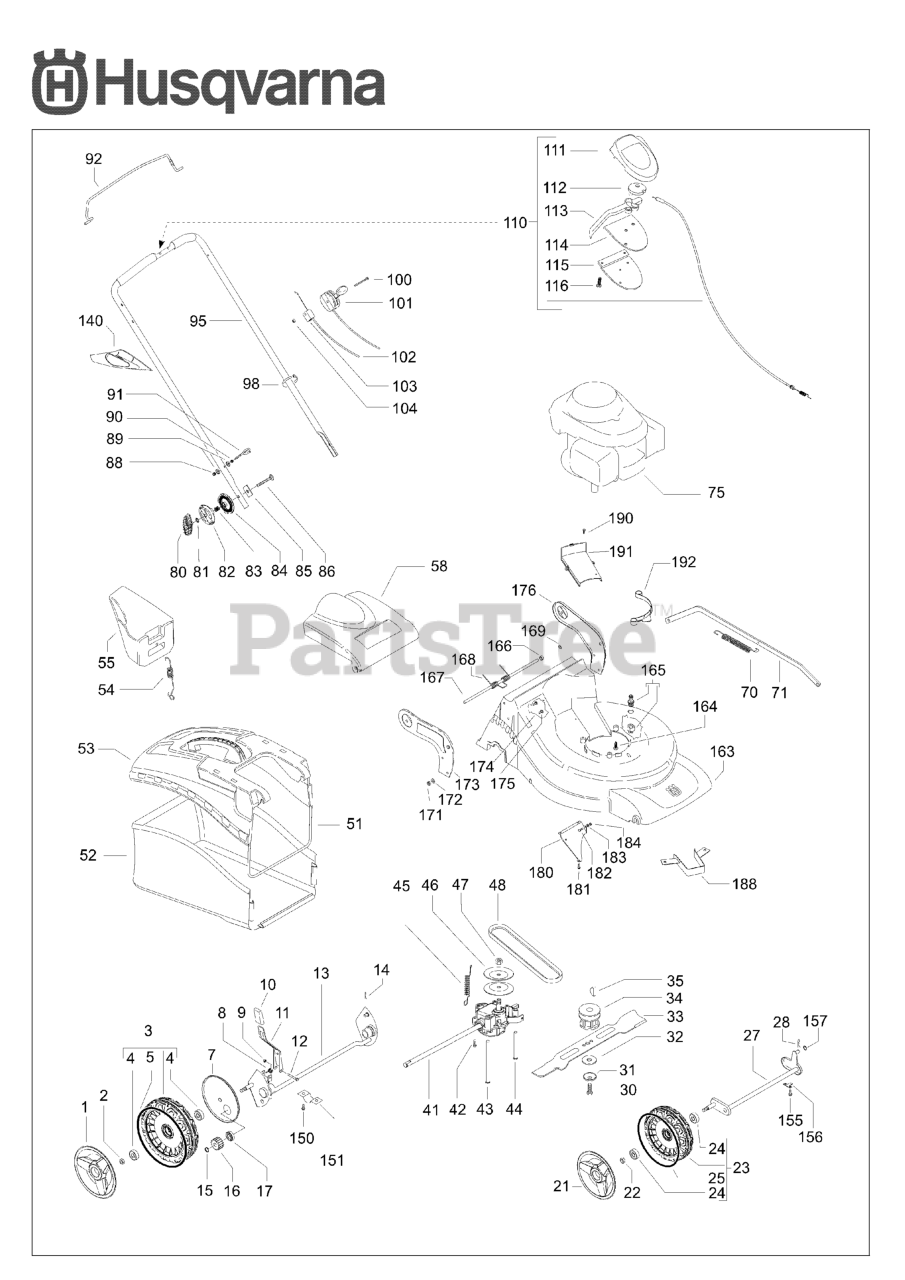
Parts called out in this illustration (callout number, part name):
11	LIFTING LEVER ASSY FOR REAR AX
51	FRAME 51 CAST
53	COVER HARD TOP
58	DEFLECTOR 51 CAST ORANGE
102	BRAKE WIRE
111	CASE.TOP.GRAY
112	PULLEY.CAM.DRIVE.CONTROL.HV
113	LEVER
114	CASE BOTTOM
115	BRACKET, DRIVE CONTROL
116	SCREW, PHILLIPS HEAD 10 X 5/8
168	SPRING 51 CAST
